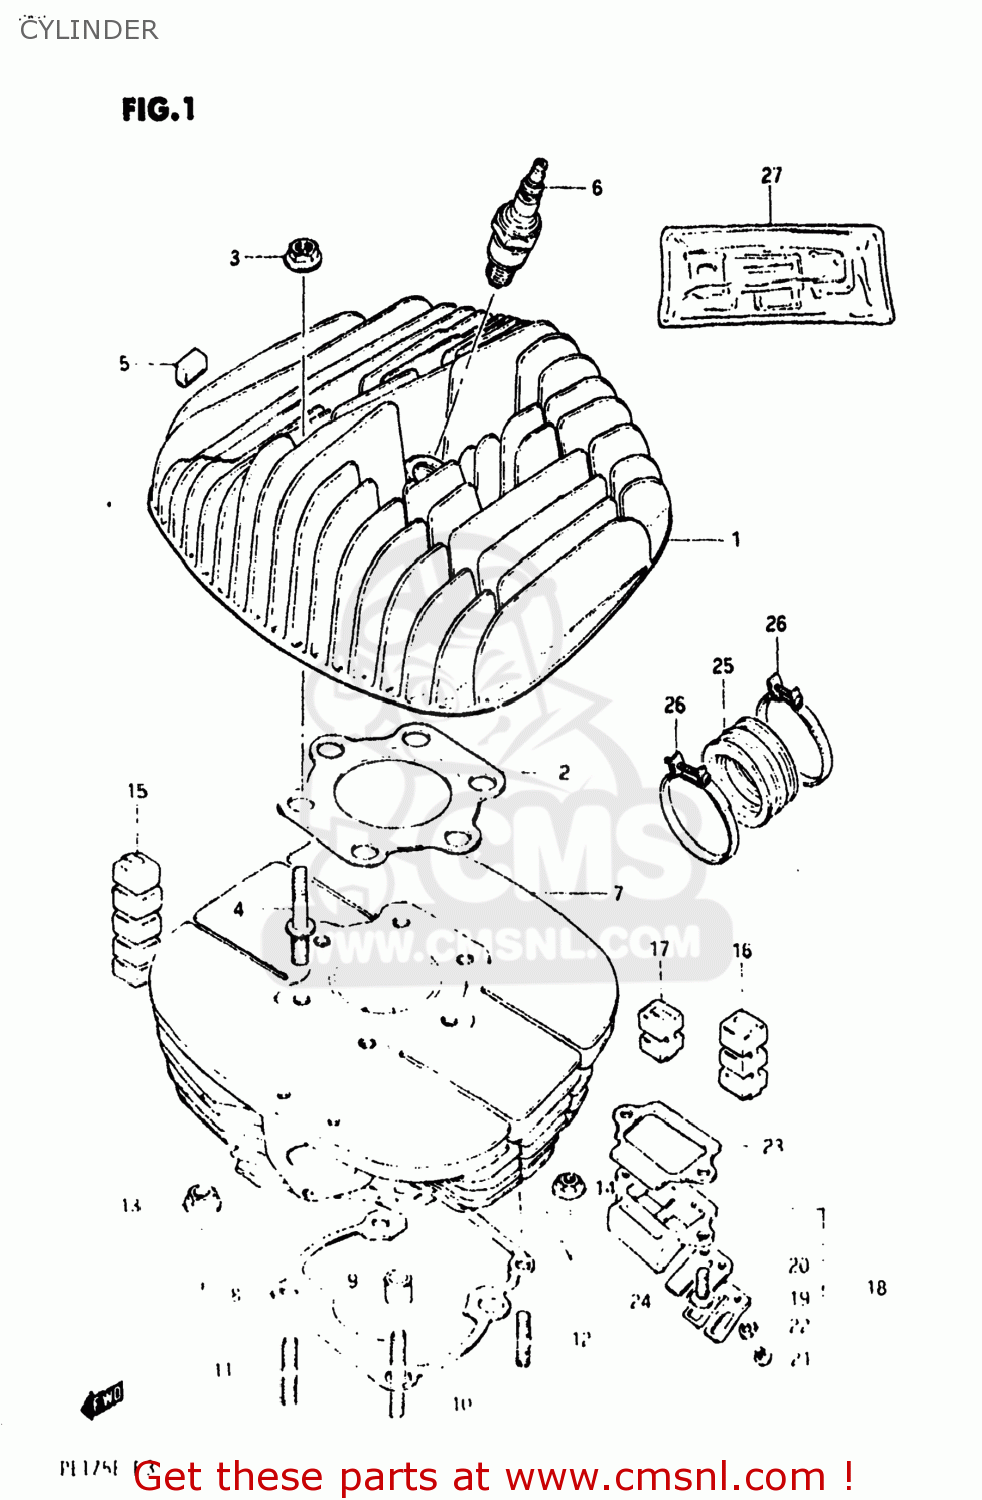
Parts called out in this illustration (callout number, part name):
1	HEAD,CYLINDER
2	GASKET,CYLINDER HEAD (NAS)
3	NUT
4	BOLT,STUD
5	PAD,CYLINDER
6	PLUG,SPARK(B10EGV)
7	CYLINDER
8	GASKET,CYLINDER (MCA)
9	PIN
10	BOLT,STUD
11	STUD 8X25
12	STUD 6X25
13	NUT
14	NUT
15	PAD,CYLINDER
16	PAD,CYLINDER
17	PAD,CYLINDER
18	VALVE ASSY,REED
19	STOPPER,REED VALVE
20	VALVE,REED
21	SCREW
22	LOCK WASHER
23	GASKET,REED VALVE (MCA)
24	SCREW
25	PIPE,INTAKE
26	CLAMP
27	GASKET SET
